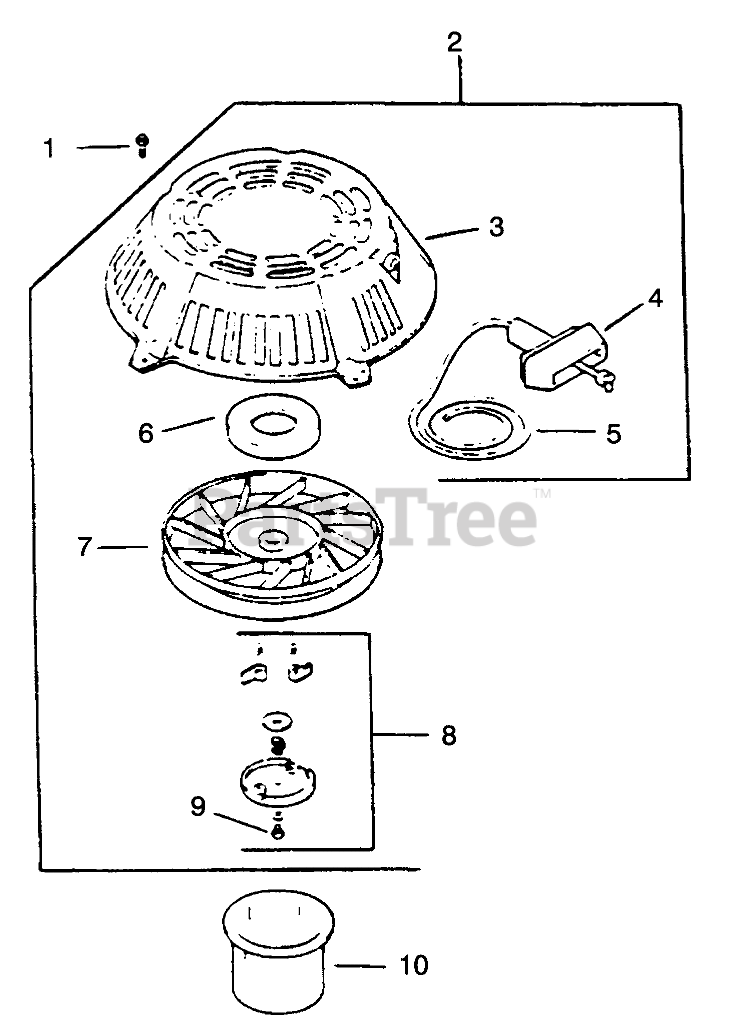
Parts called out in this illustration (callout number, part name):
1	Screw
2	Starter (Incl. Ref. #3-9)
3	Housing-Starter
4	Handle
5	Rope-Starter
6	Spring & Keeper
7	Pulley
8	Kit-Dog Replacement (Incl. Ref. #9)
9	Screw-Posidrive
10	Cup-Driver
